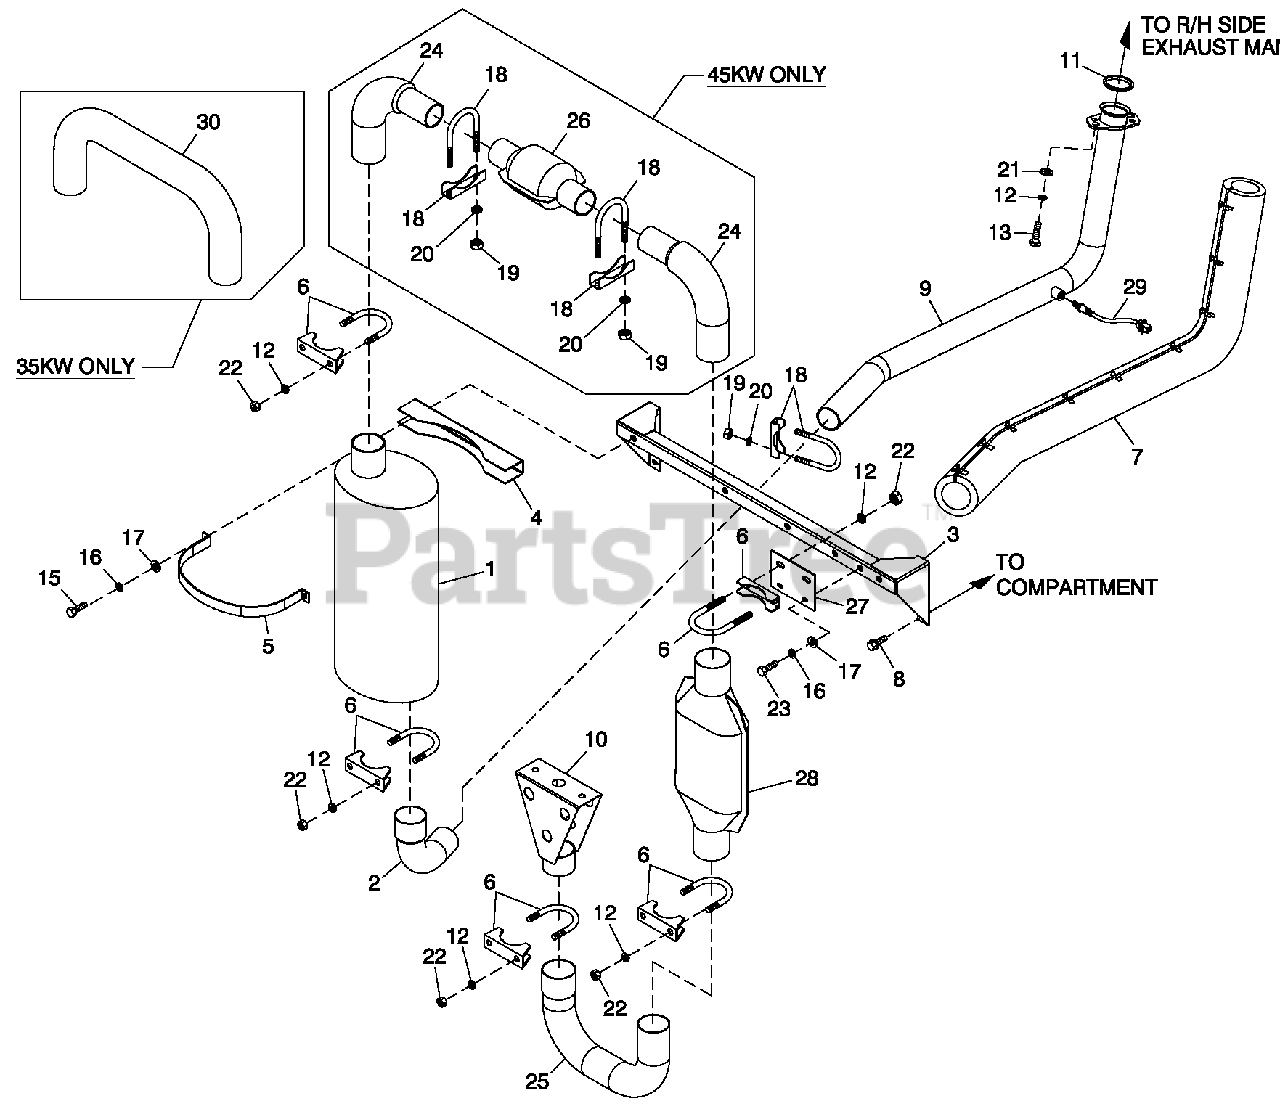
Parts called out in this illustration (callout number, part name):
1	MFLR 7"X9"X18-1/2"2-1/2"IN/OUT
2	EXHAUST ELBOW 2"ID X 2-1/2"OD
3	BRACKET MUFFLER
4	MUFFLER BRACKET STIFFENER
5	MUFFLER STRAP
6	BOLT U 3/8-16 X 2.62
7	EXHAUST BLANKET 988MM (C2)
8	SCREW THF M6-1 X 16 N WA Z/JS
9	PIPE EXHAUST G2 EMISSIONS
10	DIFFUSER EXHAUST WELDMENT
11	GASKET EXHAUST RING
12	WASHER LOCK 3/8 SS
13	SCREW HHC 3/8-16 X 1-3/4 SS
15	SCREW HHC M6-1.0 X 35 G8.8 BLK
16	WASHER LOCK M6-1/4
17	WASHER FLAT 1/4-M6 ZINC
18	BOLT U 5/16-18 X 2.25 (35KW ONLY)
19	NUT HEX 5/16-18 STEEL (35KW ONLY)
20	WASHER LOCK M8 SS (35KW ONLY)
21	WASHER FLAT 3/8 SS
22	NUT HEX 3/8-16 STEEL
23	SCREW HHC M6-1.0 X 16 G8.8
24	EXHAUST 90D ELBOW 2"OD X2.5"OD (45KW ONLY)
25	PIPE, EXHAUST MUFFLER OUT
26	CATALYST, CPL PRECAT (45KW ONLY)
27	PLATE, CATALYST MOUNTING
28	CATALYST AF-RATIO
29	SENSOR OXYGEN
30	PIPE, EXHAUST CROSSOVER EMSSM (35KW ONLY)
